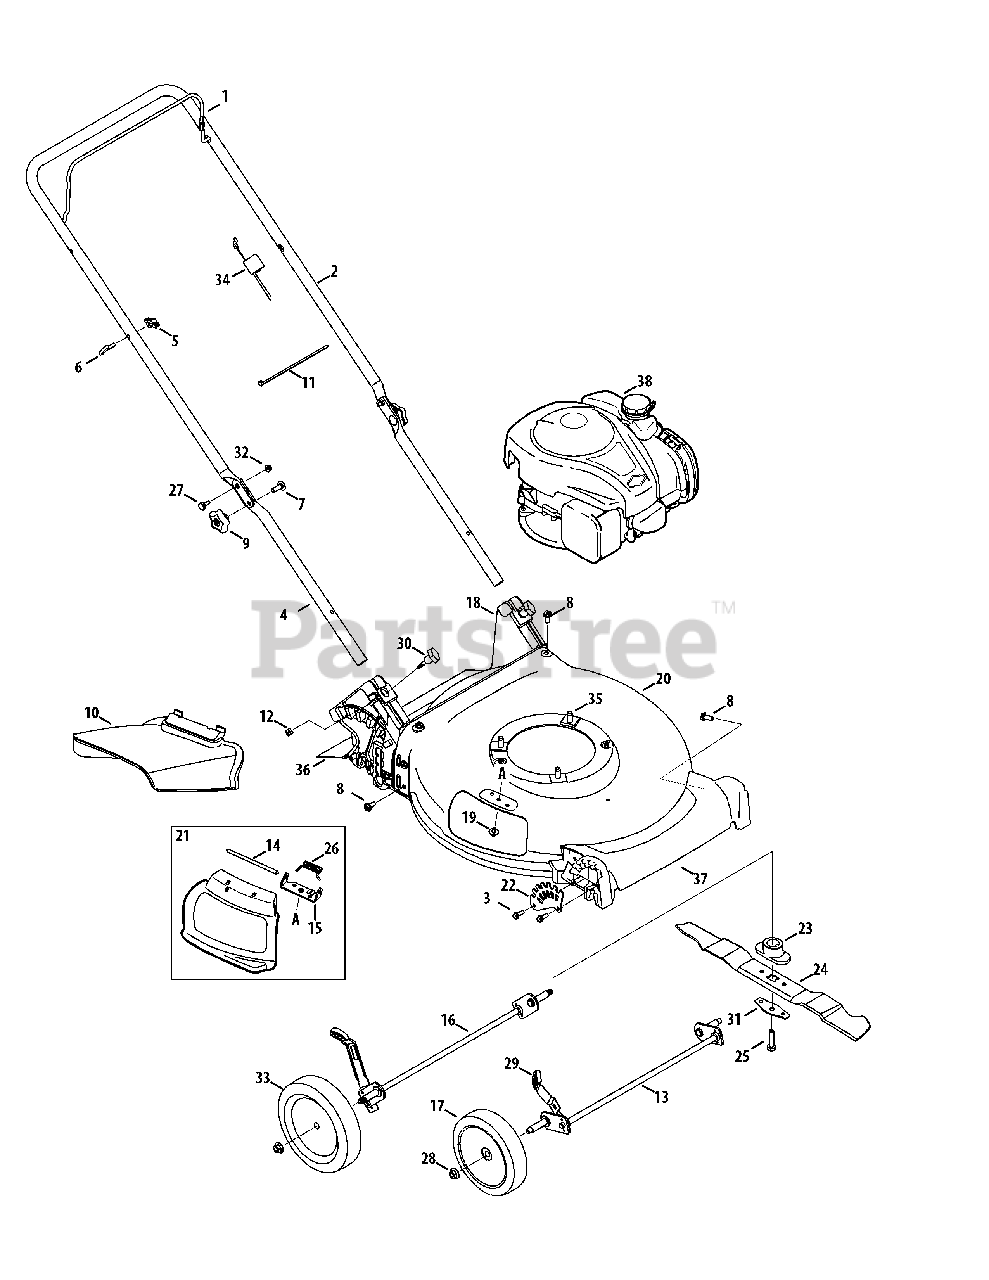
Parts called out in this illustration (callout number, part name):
1	Blade Control
2	Upper Handle
3	Screw, 1/4-15 x .750
4	Lower Handle
5	Wing Nut
6	Rope Guide
7	Carriage Screw, 5/16-18
8	Screw, 5/16-14 x .750
9	Hand Knob
10	Side Chute
11	Cable Tie
12	Nut, Sq., 1/4-20
13	Front Axle Assembly
14	Hinge Pin
15	Chute Deflector Bracket
16	Rear Axle Assembly
17	Wheel, 7 x 1.8
18	Rear Baffle
19	Screw, 1/4-20 x .500
20	Deck - 21"
21	Hinged Mulch Plug Assembly
22	Front Height Adjuster Plate
23	Blade Adapter
24	Mulching Blade
25	Screw , 3/8-24 x 1.50
26	Torsion Spring
27	Sldr. Screw, .375 x .126 x 1/4-20
28	Flange Lock Nut, 3/8-16
29	Adjustment Lever Knob
30	Wing Nut
31	Blade Bell Support
32	Nut, Flange Lock, 1/4-20
33	Wheel, 8 x 1.8
34	Control Cable
35	TT Screw, 3/8-16 x 1.0
36	Trail shield
37	Front Cover
38	Engine - 09P702-0008-F1
